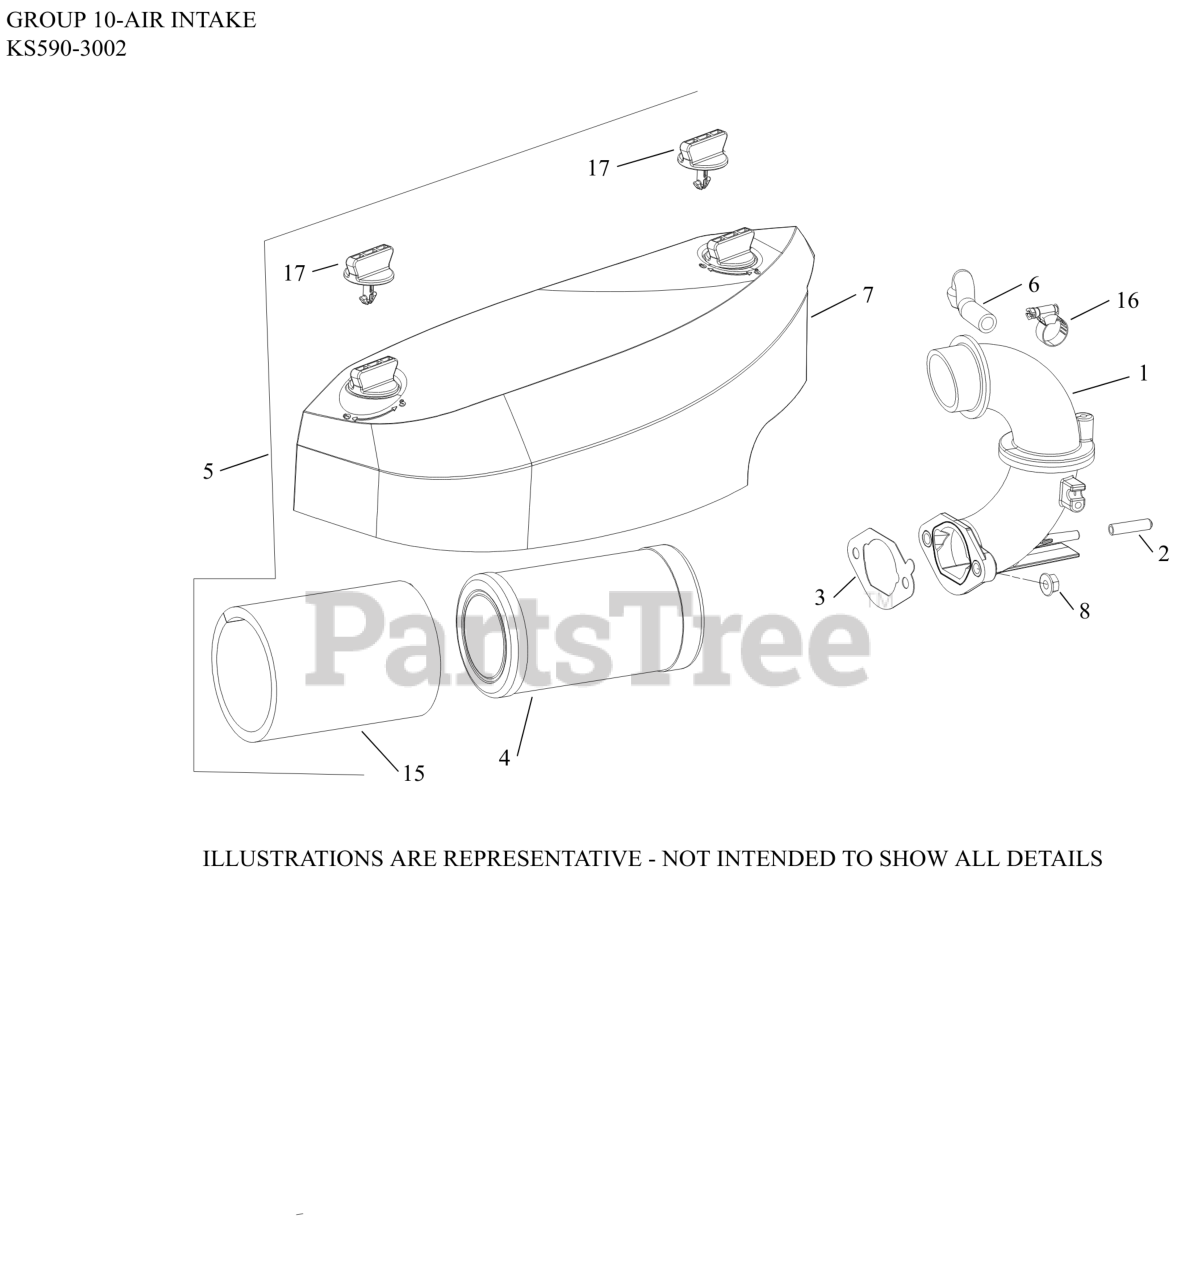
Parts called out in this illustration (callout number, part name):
1	ADAPTER, AIR CLEANER ASSY
2	CAP, MASKING
3	GASKET, CARBURETOR
4	ELEMENT, AIR FILTER
5	AIR FILTER KIT (STD)
6	HOSE, BREATHER
7	COVER, AIR CLEANER ASSY
8	NUT, FLG M6X1.0
15	ELEMENT, PRE-CLEANER
16	CLAMP, HOSE (KM)-USE 25 237 31-S
17	KNOB, AIR CLEANER COVER
